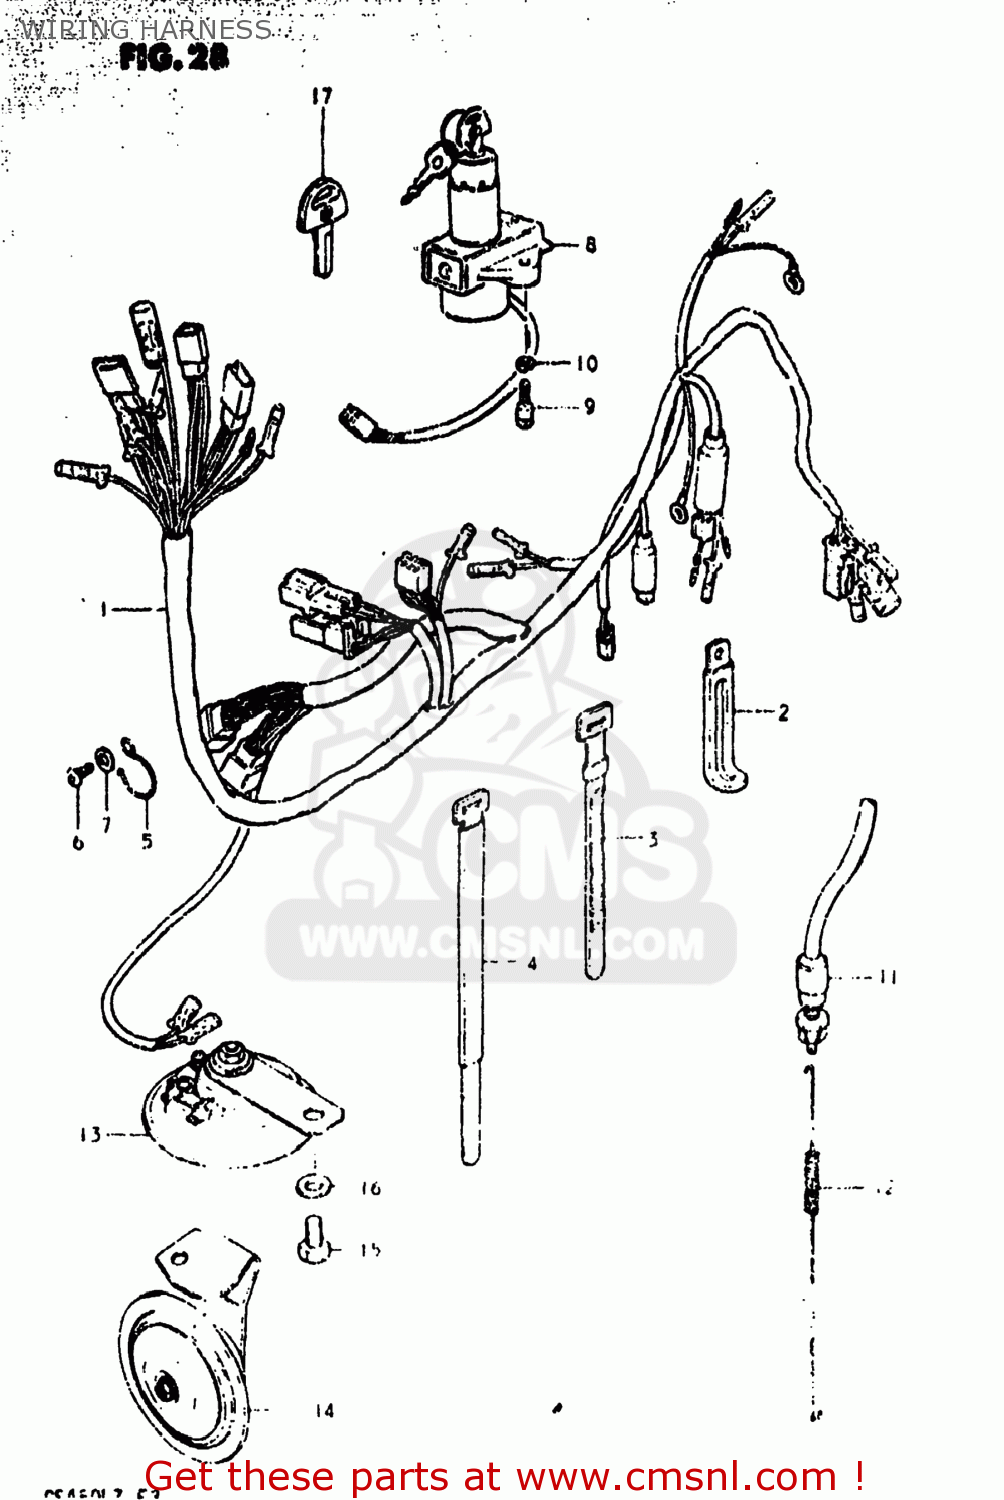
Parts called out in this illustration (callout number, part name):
1	HARNESS,WIRING
2	CLAMP
3	CLAMP(L:80)
4	CLAMP
5	GUIDE,WIRING HARNESS
6	SCREW 6X12
7	WASHER
8	LOCK ASSEMBLY,STEERING
9	BOLT
10	LOCK WASHER
11	SWITCH ASSEMBLY,STOP LAMP
12	SPRING
13	HORN ASSEMBLY,LOW PITCH
14	HORN ASSEMBLY
15	BOLT 8X12
16	WASHER
17	KEY,BLANK
